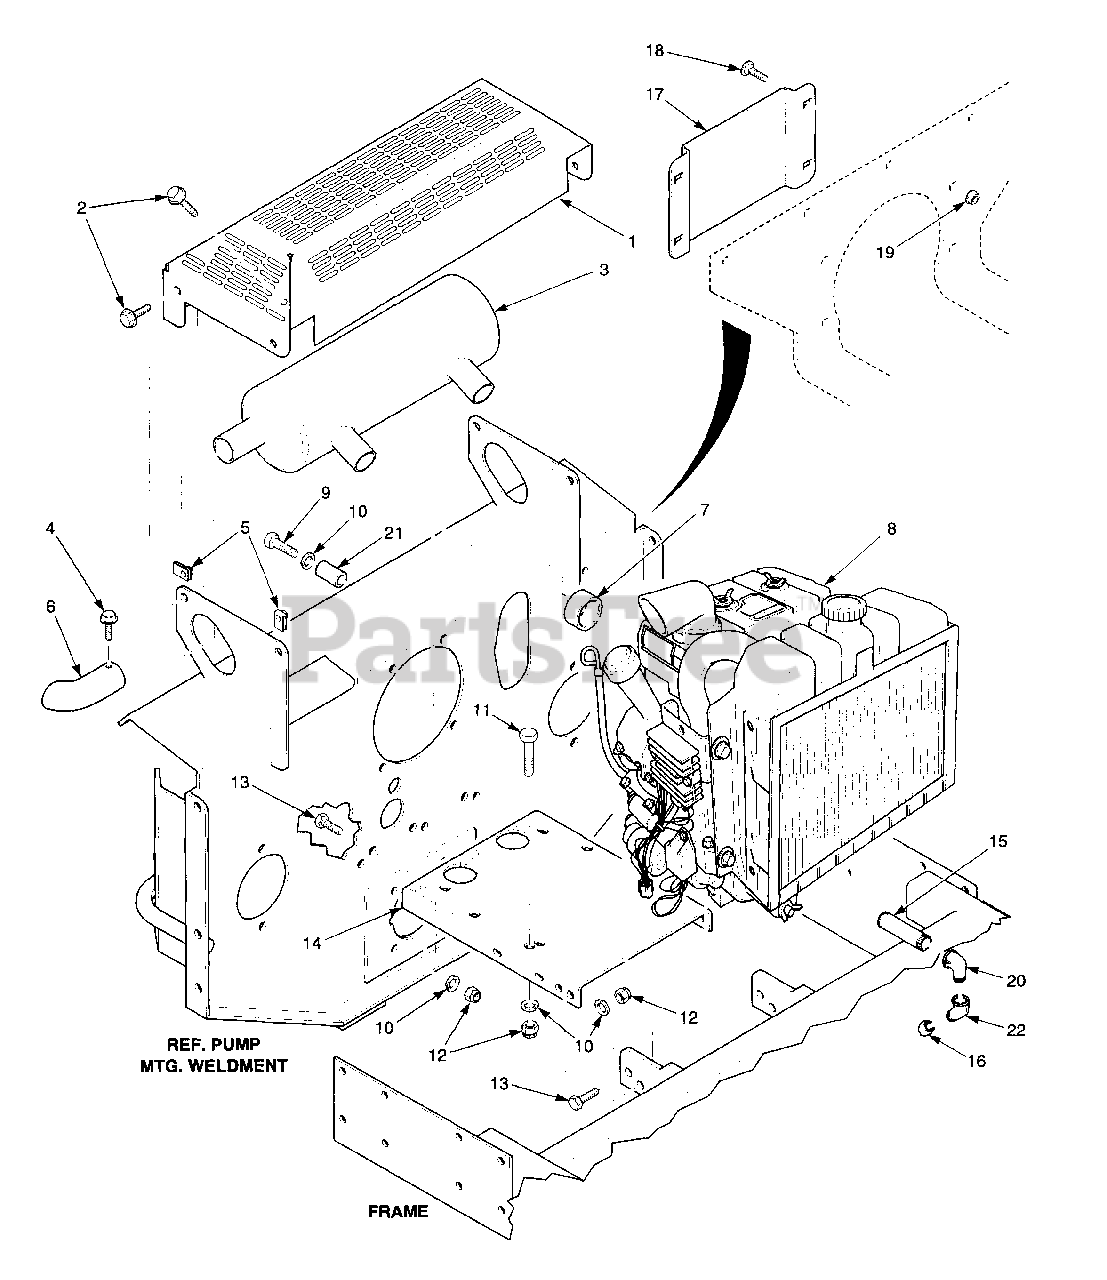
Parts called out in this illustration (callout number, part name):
1	Muffler Guard
2	Screw, Hex Serrated Flange 1/4-20 x 3/4"
3	Muffler, Part Of Engine
4	Screw, #10-16 x 1/2"
5	U-Nut, 1/4-20
6	Exhaust Elbow (Kawasaki)
7	Spacer, Engine (Kawasaki)
8	Engine, Kawasaki 22KA
9	Bolt, M8-1.25 x 25 Grade 8.8
10	Lockwasher, 3/8" Spring
11	Bolt, Hex Head 3/8-16 x 1-3/4"
12	Nut, Hex Elastic Stop 3/8-16
13	Bolt, Hex Head 3/8-16 x 1-1/4"
14	Plate, Engine Mounting
15	Extension, Oil Drain 4"
16	Pipe Cap, Hex 3/8"
17	Rear Cover
18	Bolt, Carriage 5/16-18 x 3/4"
19	Nut, Hex Serrated Flange 5/16-18
20	Street Elbow, 3/8" NPT
21	Spacer, Engine Bolt
22	Street Elbow, 45 Deg.-3/8" NPT
